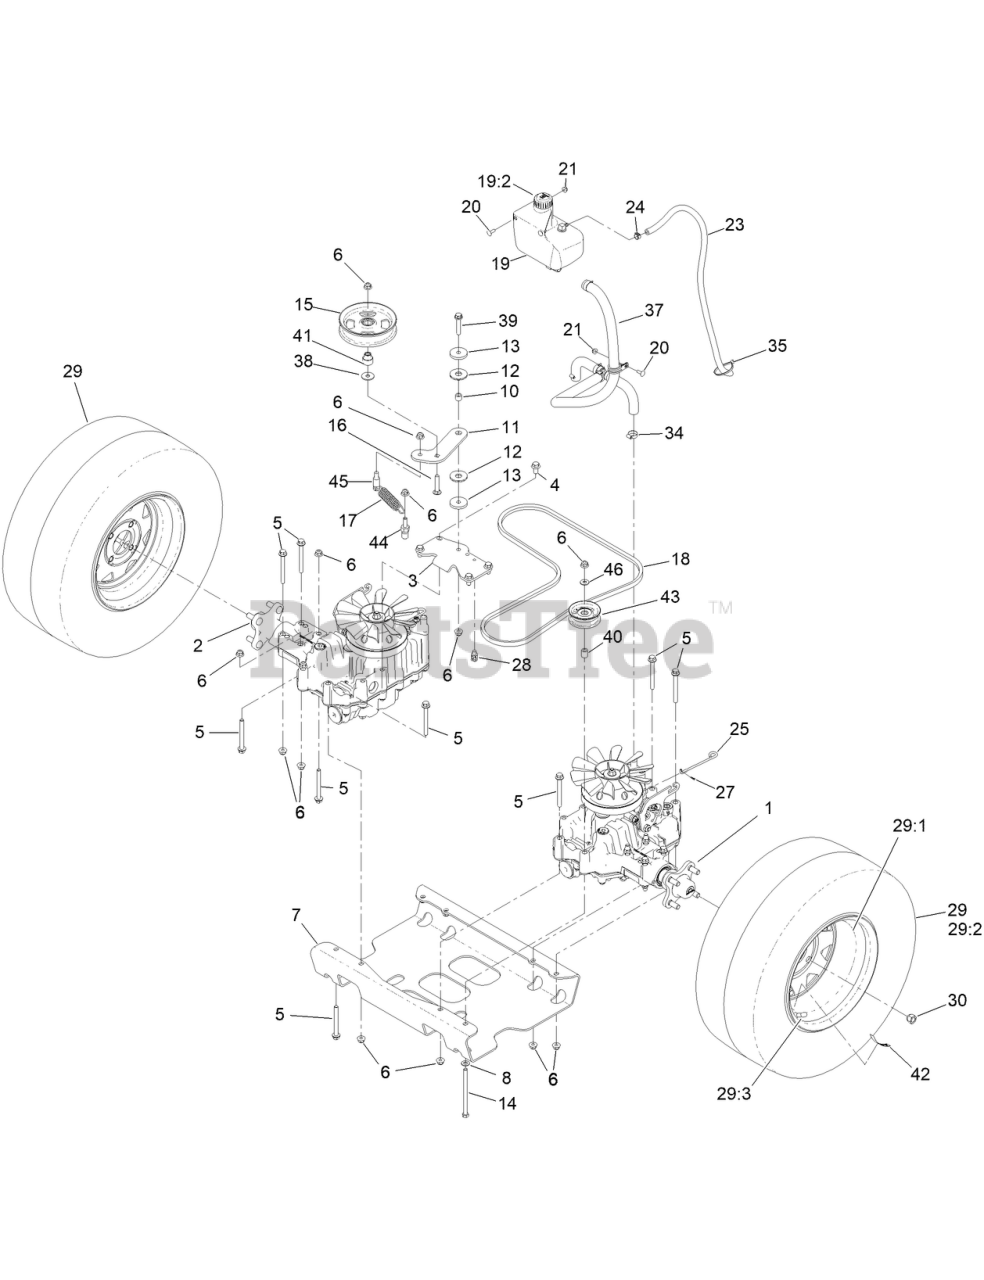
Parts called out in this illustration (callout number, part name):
1	LH TRANSMISSON (TZT13SY)
2	RH TRANSMISSON (TZT13SX)
3	PLATE, SUPPORT, TRANSAXLE
4	SCREW-BSHS
5	SCREW-HHF
6	NUT-HF, NI
7	PLATE-HYDRO
8	WASHER-FLAT
10	BUSHING-LEVER, LIFT
11	PLATE-ARM, IDLER
12	WASHER-FRICTION, COMPOSITE
13	WASHER-PLAIN
14	SCREW-HH
15	PULLEY-IDLER,FLAT
16	SCREW-CARR
17	SPRING-EXTENSION
18	BELT-V
19	TANK-HYD
19:2	CAP-VENTED
21	NUT-HF
23	HOSE-FUEL
24	CLAMP-HOSE
25	ROD-BYPASS
27	PIN-HAIR
28	CLIP, FIR TREE
29	WHEEL AND TIRE ASM
30	NUT-LUG
34	CLAMP-HOSE
35	TIE-CABLE
37	HYD HOSE ASM
38	WASHER-HARDENED
39	SCREW-HHF
40	SPACER-WHEEL
41	BUSHING-IDLER
42	DECAL-TORQUE, WHEEL HUB LUG
43	PULLEY-IDLER, FLAT
44	PIN-ANCHOR, SPRING
45	ANCHOR-SPRING
46	NUT-FLANGE, NI
